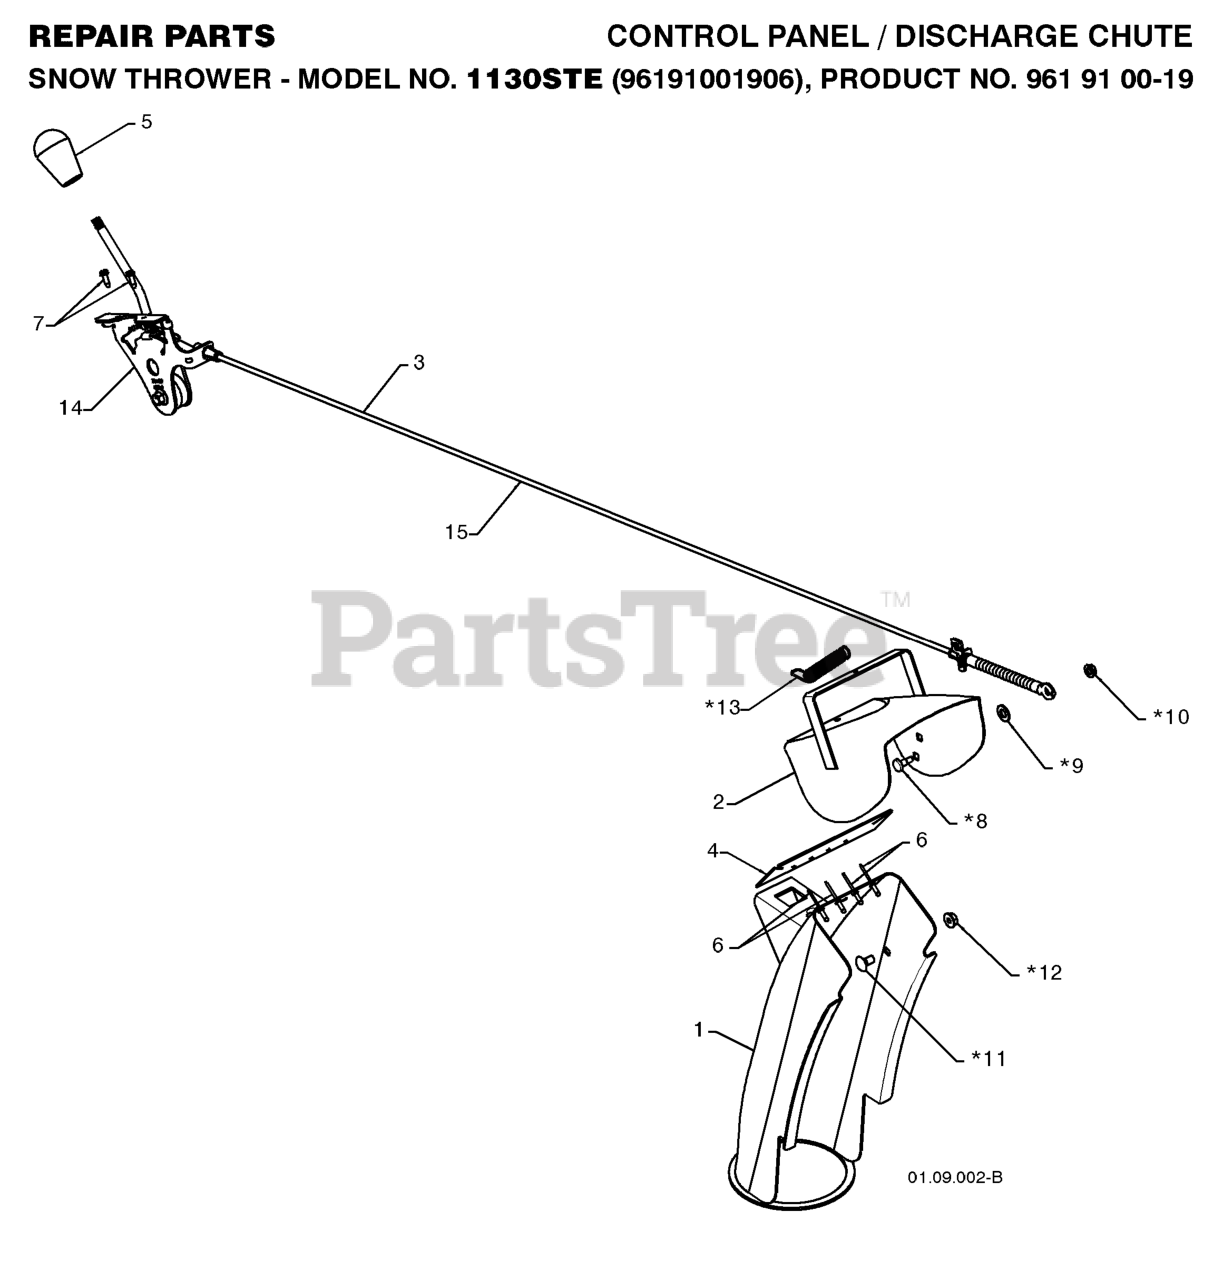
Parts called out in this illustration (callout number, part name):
2	SHAFT.ASM.LIFT.CROSS.H
3	LEVER.LIFT.HANDLE.GT
7	GRIP.HANDLE.LIFT.PVC.BLACK
10	SPRING.TORSION.LIFT.HANDLE
87	PIN.COTTER.7/16.BOW TI.
88	SPRING.LIFT.ASSIST.GT2
89	WASHER.CLEAR.ZINC
90	PIN.COTTER.5/16.BOW TI
91	LINK.LIFT.ASM.REAR.GT.
97	SCREW, 3/8-16X3/4
98	LINK.ASM.SUSP.FRONT.MWR.10.5
